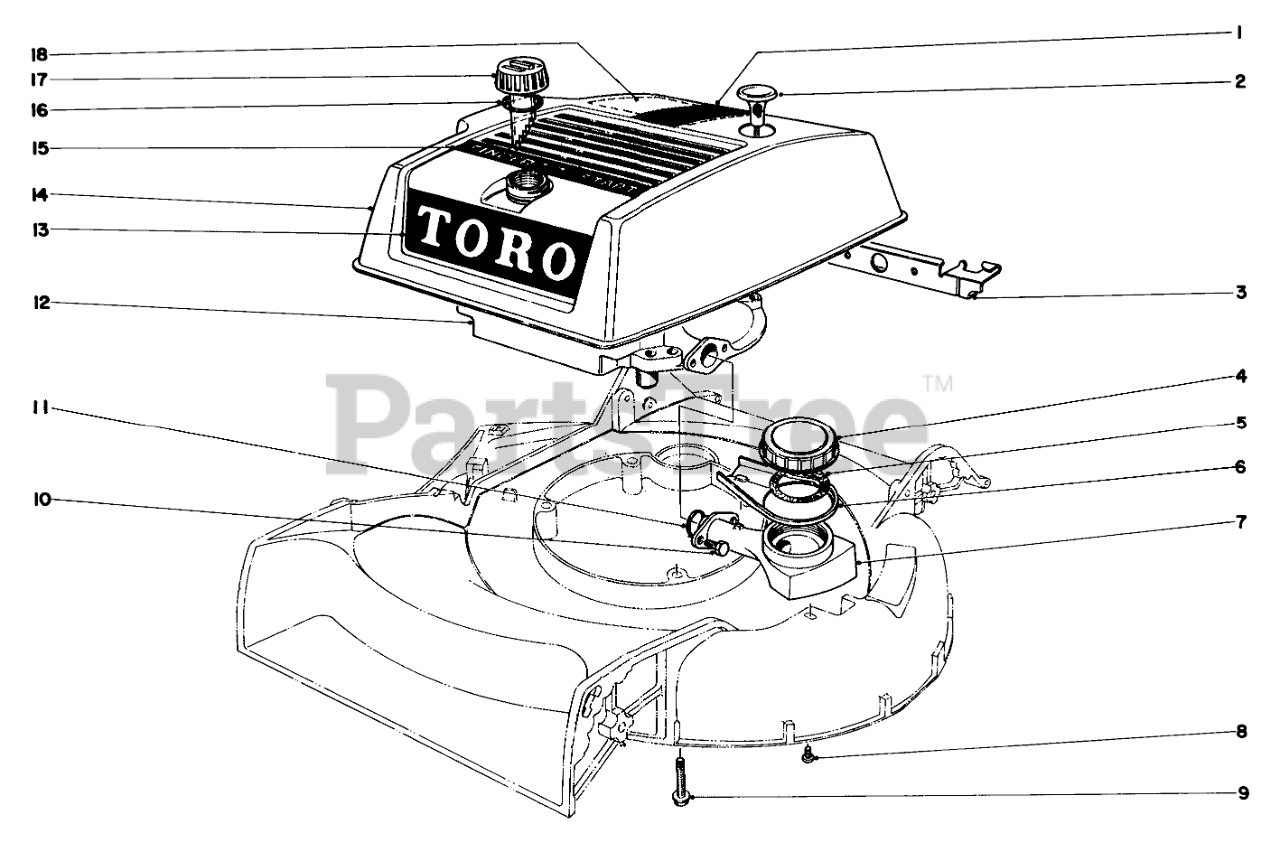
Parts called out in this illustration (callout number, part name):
1	Decal
2	Rope Handle
3	Shroud Bracket
4	Oil Gauge Cap
5	VISUAL OILER GASKET
6	Spout
7	Oil Gauge
8	Screw
9	3/8-16 X 2-3/4 CAPSCR
10	SCREW-HH
11	O RING
12	Engine
13	Decal-Toro
14	Shroud
15	Decal
16	Gasket
17	Gas Cap
18	Decal-Maintenance
